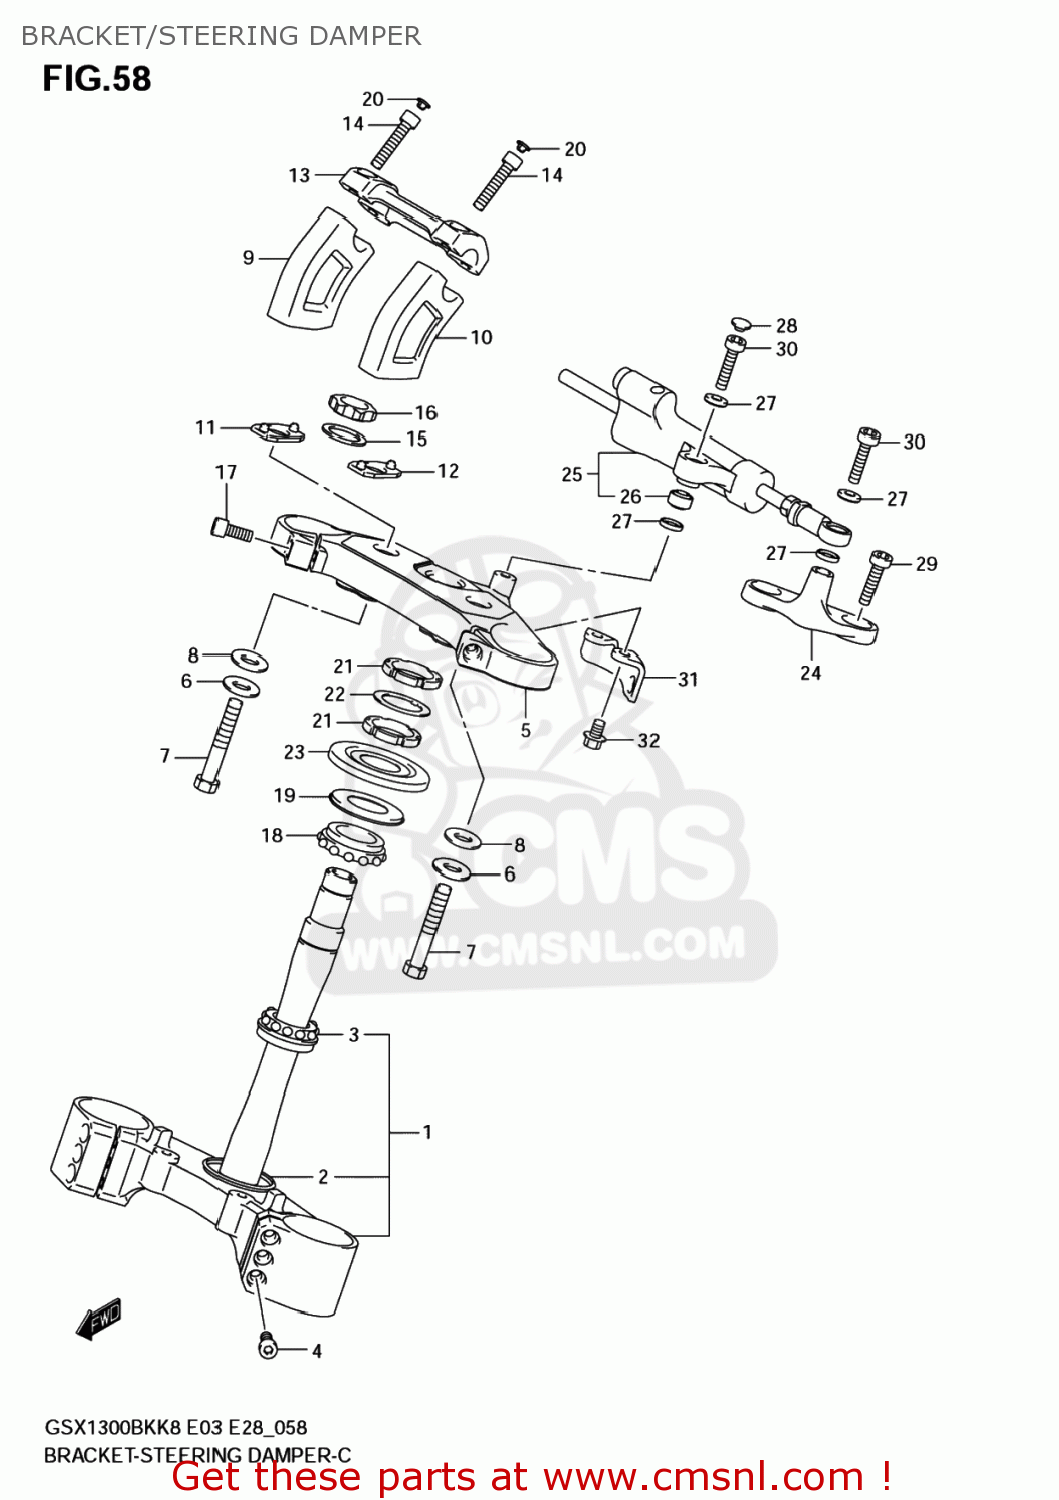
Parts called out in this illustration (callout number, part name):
1	BRACKET,UNDER
2	SEAL,STEERING LWR
3	BEARING(30X55X17)
4	BOLT
5	BRACKET,UPR
6	WASHER
7	BOLT
8	RUBBER,HANDLE HOLDER
9	HOLDER,LWR,R
10	HOLDER,LWR,L
11	RUBBER,HANDLE HOLDER
12	RUBBER,HOLDER
13	HOLDER,UPR
14	BOLT
15	WASHER
16	NUT
17	BOLT
18	BEARING(30X55X17)
19	SEAL,STEERING LWR
20	CAP(OD:11)
21	NUT,STEERING STEM
22	WASHER,STEERING STEM
23	COVER,STEERING UPR
24	BRACKET,STEERING DAMPER
25	DAMPER ASSY,STEERING
26	BEARING(8X17.5X11)
27	SEAL,PILLOW BALL,DUST
28	CAP(OD:11)
29	BOLT
30	BOLT
31	PLATE,STEERING LOCK
32	BOLT(8X16)
